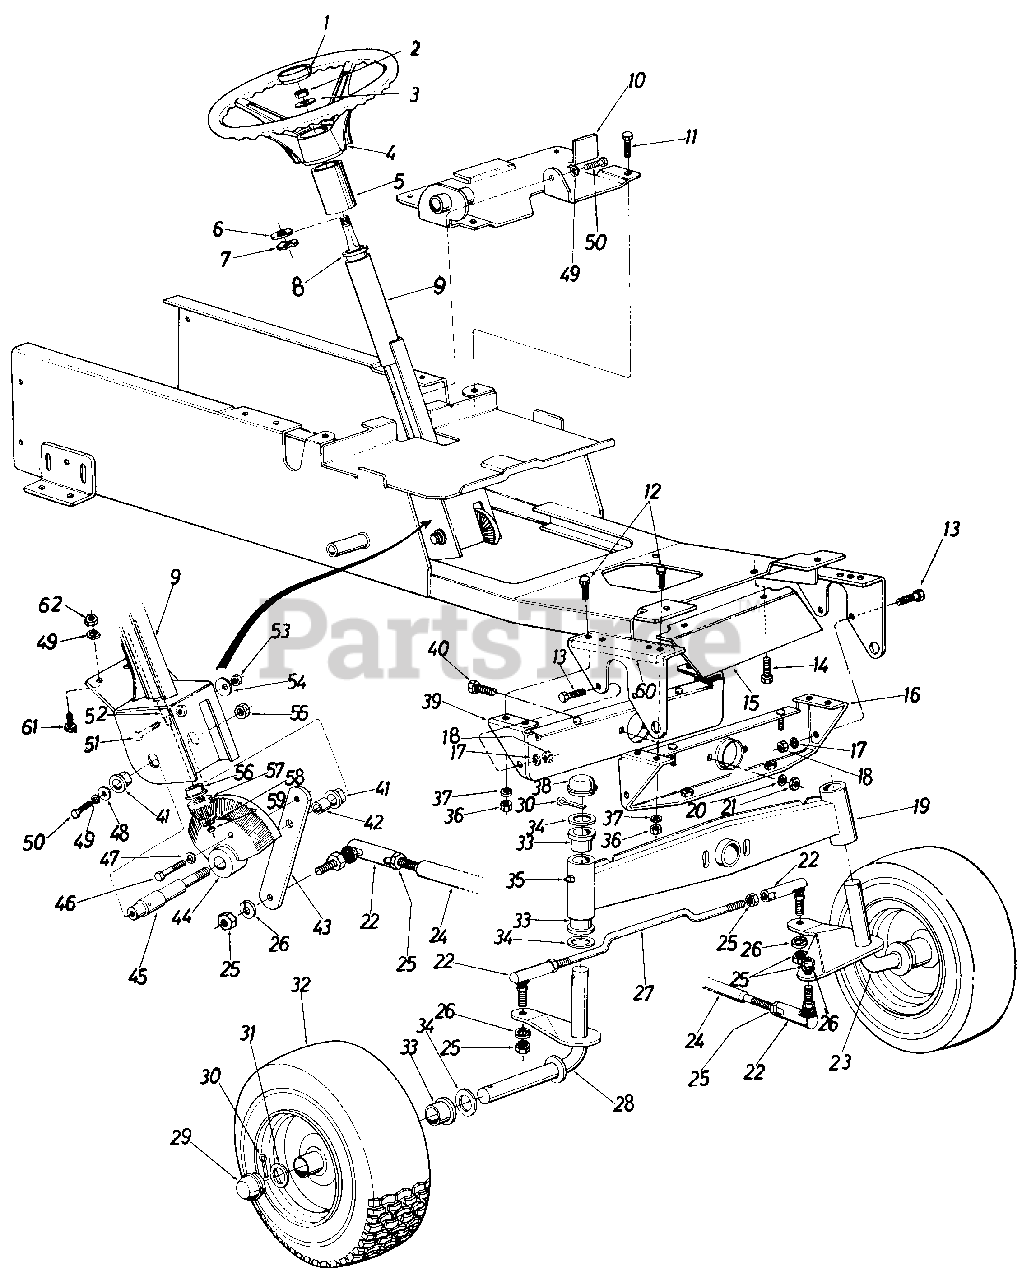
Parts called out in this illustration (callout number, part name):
1	Steering Wheel Cap
2	Hex Cent. L-Nut 5/16-18 Thd.
3	Bell-Wash.
4	Steering Wheel
5	Steering Bellow
7	Wave Wash. .660" I.D. x .88" O.D.
8	Ball Brg. .63" I.D. x 1.38" O.D.
10	Dash Panel Base Plate Ass'y.
11	Hex Self-Tap Scr. 3/8-16 x .75" Lg.
12	Hex Scr. 3/8-16 x 1.50" Lg.
13	Hex Scr. 3/8-16 x 1.00" Lg.
14	Hex Wash. S.F. Tap Scr. 3/8-16 x 1.25" Lg.
15	Dust Shield
18	Hex Nut 3/8-16 Thd.
19	Pivot Bar Ass'y.
20	Bell-Wash. 3/8" Scr.
21	Hex Cent. L-Nut 3/8-16 Thd.
22	Drag Link End
23	Axle Ass'y. L.H.
24	Drag Link
25	Hex Nut 1/2-20 Thd.
26	L-Wash. 1/2" Scr.*
27	Tie Rod
28	Axle Ass'y. R.H.
29	Dust Cover
30	Cotter Pin 3/16" Dia. x 1.50" Lg.
31	Fl-Wash. 1.00" I.D. x 1.62" O.D.
33	Flange Brg. 1.00" I.D.
34	Fl-Wash. 1.00" I.D. x 1.62" O.D.
35	Grease Fitting
36	Hex Nut 3/8-16 Thd.
37	L-Wash. 3/8" Scr.
38	Dust Cover
40	Hex Scr. 3/8-16 x 2.50" Lg.
41	Flange Brg. w/Flats .753" I.D.
42	Steering Gear Shaft Spacer
43	Steering Arm
44	Bevel Gear
45	Steering Gear Shaft
46	Hex Scr. 3/8-16 x 1.50" Lg.
47	L-Wash. 3/8" Scr.
48	Fl-Wash. .406" I.D. x 1.25" O.D.
49	L-Wash. 3/8" Scr.
50	Hex Scr. 3/8-16 x .75" Lg.
51	Nylon Cup
52	Steering Shaft
53	Hex Bolt 3/8-16 x 1.5" Lg.
54	Hex Jam Nut 3/8-16 Thd.
55	Hex Ins. L-Nut 1/2-20 Thd.
56	Hex Flange Brg. .630 I.D.
57	Pinion Gear
58	Fl-Wash. 3/8" Dia.
59	Hex Cent. L-Nut 5/16-24 Thd.
62	Hex Nut 3/8-24 Thd.
